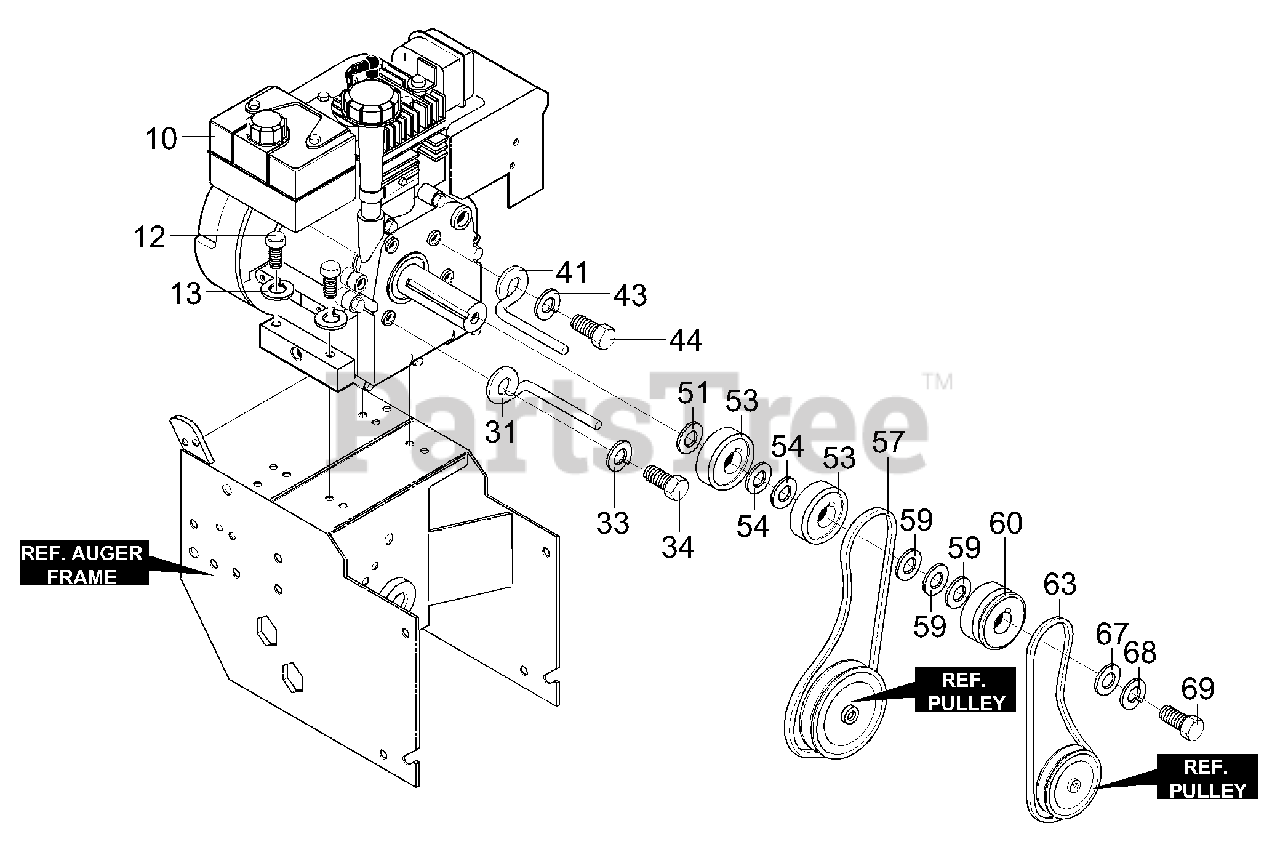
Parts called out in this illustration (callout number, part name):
10	ENGINE 7HP TEC (SEE ENGINE MANUAL)
12	SCREW, 5/16-18 X .75
13	WASHER, HVSPTLK .328X.60X.09
31	GUIDE, ROD BELT RH
33	WASHER, HVSPTLK .328X.60X.09
34	SCREW 5/16-24X.625
41	GUIDE, ROD BELT LH
43	WASHER, HVSPTLK .328X.60X.09
44	SCREW 5/16-24X.625
51	WASHER, CRANKSHAFT
53	PULLEY, HALF V3L 2.00X.752ID
54	FLATWASHER, .752X.91X.02
57	BELT, V 3L 33.13LG
59	FLATWASHER, .765X1.12X.06
60	PULLEY, ENGINE V 4L
63	BELT, V 4L 36.6LG
67	FLATWASHER
68	WASHER, REGSPTLK .393X.60X.10
69	SCREW 3/8-24 X 1.00 NYL
